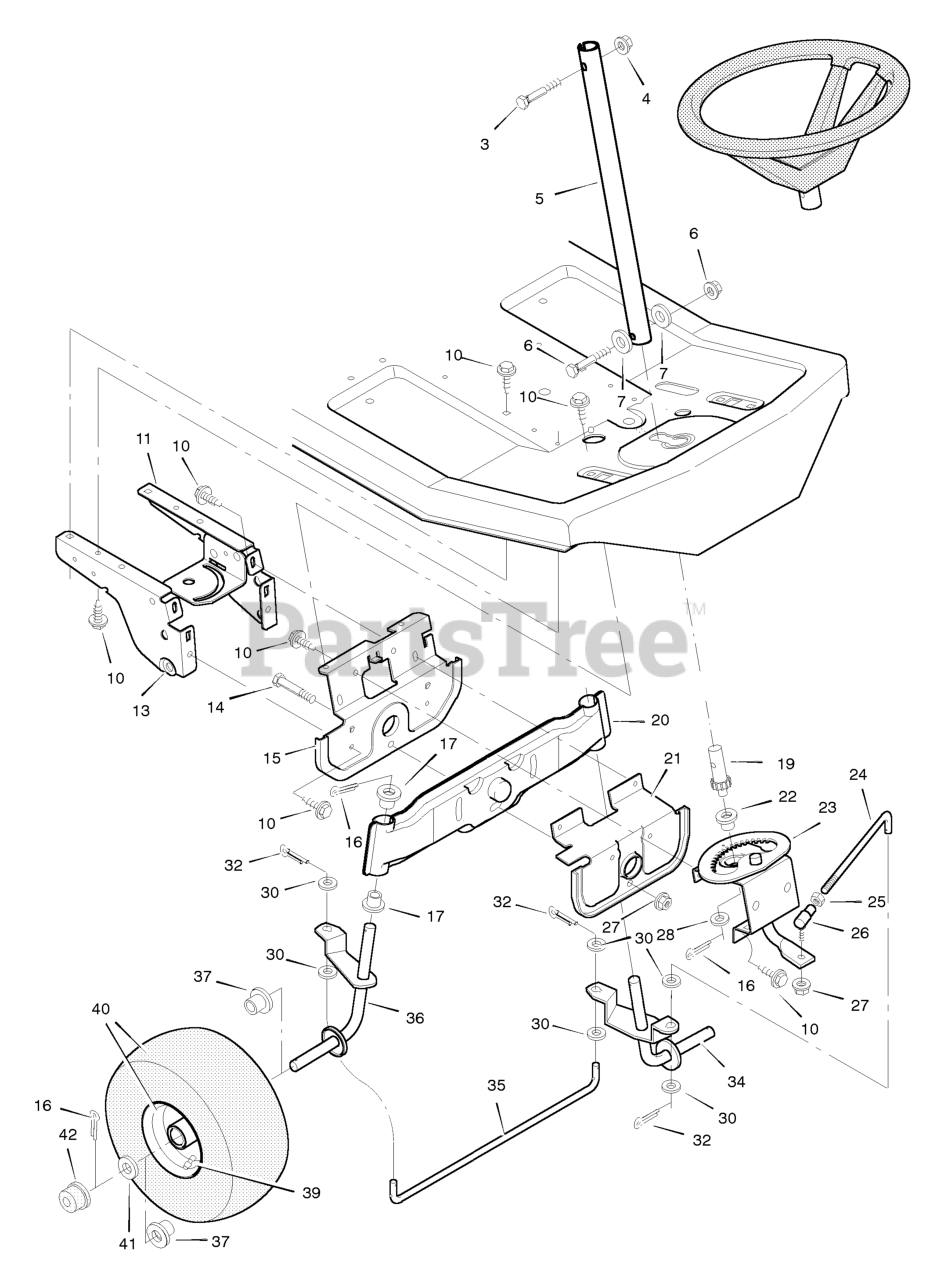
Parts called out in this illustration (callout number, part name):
1	Steering Wheel
3	Bolt, Hex
4	Locknut, Flange
5	Post, Steering
6	Nut, Hex
7	Washer
11	Plate, Left Suspension
13	Plate, Right Suspension
14	Bolt, Hex
15	Support, Front Axle
16	Pin, Cotter
17	Bearing, Spindle
19	Gear, Pinion
20	Axle Assembly, Front
21	Hanger Assembly, Front Axle
22	Bearing
23	Sector Assembly
24	Rod, Drag Link
25	Ball Joint, Steering
26	Nut, Hex
27	Locknut, Flange
28	Washer
30	Washer
32	Pin, Cotter
34	Spindle Assembly, Left
35	Rod, Tie
36	Spindle Assembly, Right
37	Bearing, Wheel
39	Valve Stem
40	Wheel & Tire Assembly
42	Cap, Hub
